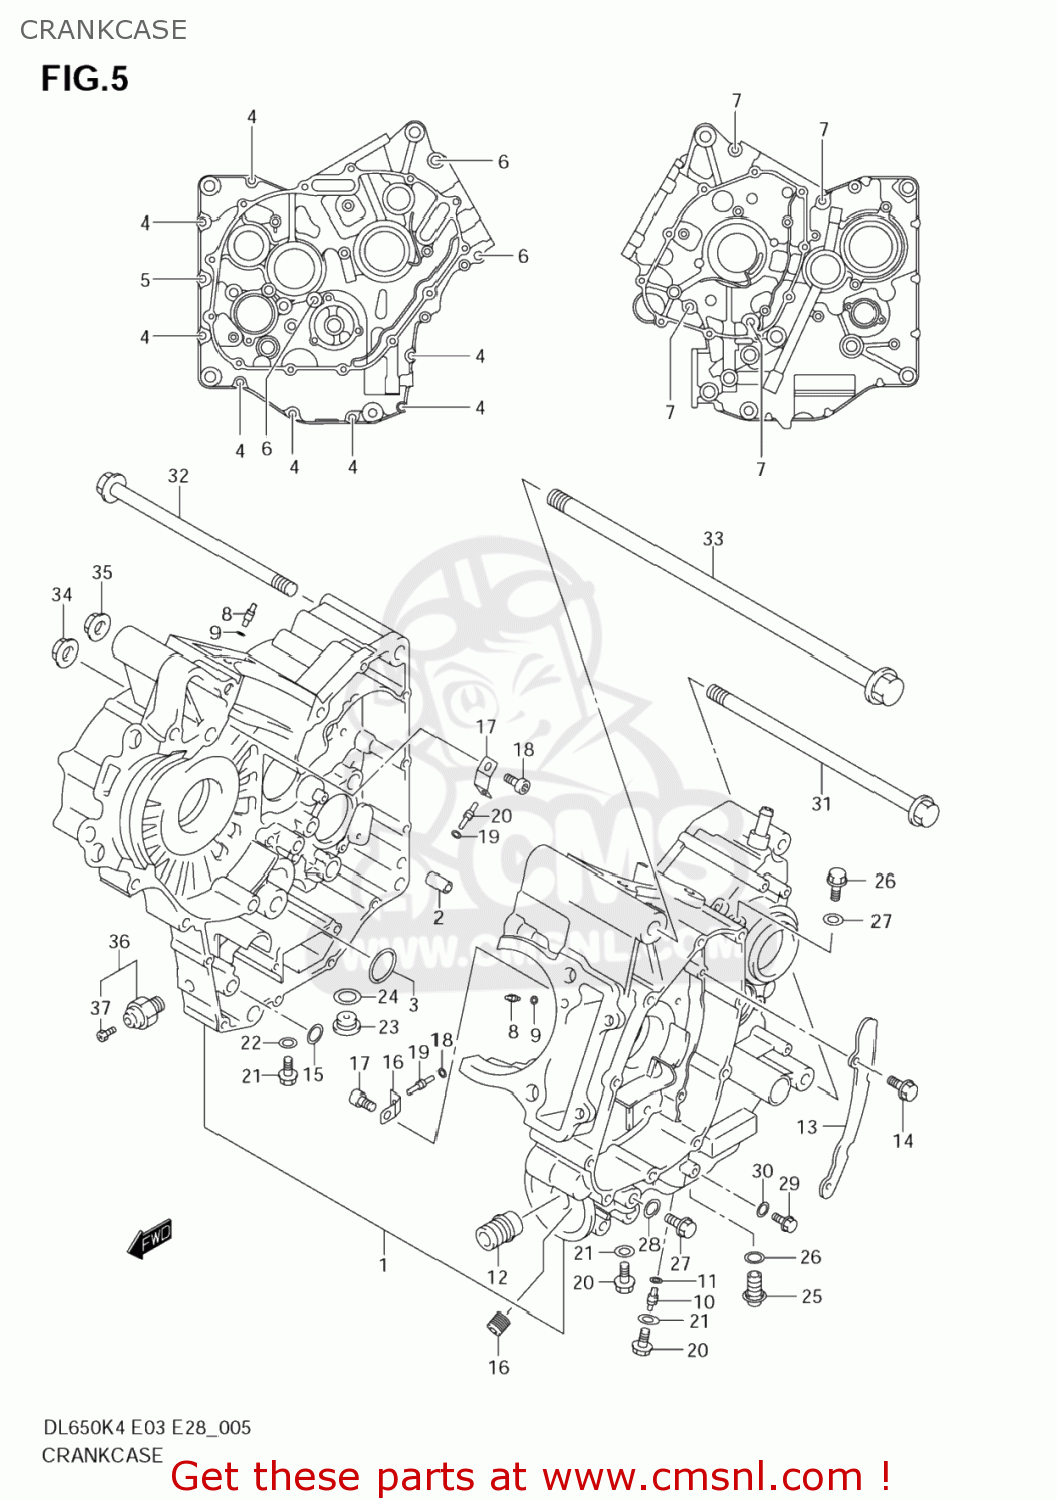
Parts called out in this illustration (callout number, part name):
1	CRANKCASE SET
2	PIN(8.4X11X20)
3	O RING(D:2.4,ID:15.8)
4	BOLT
5	BOLT
6	BOLT
7	BOLT
8	JET,AIR(14)
9	O RING(D:1.2,ID:4)
10	JET,AIR(14)
11	O RING(D:1.2,ID:4)
12	UNION,OIL STAND
13	PLATE,OIL SEPARATOR
14	BOLT
15	O RING(D:1.9,ID:12.6)
16	JET,OIL GALLERY(3.6)
17	PLATE,PISTON COOLING JET
18	BOLT(6X12)
19	O RING(D:1.2,ID:4)
20	JET(13)
21	BOLT
22	GASKET(8.2X14X1) (NAS)
23	PLUG,16X8
24	GASKET(16X22X2) (NAS)
25	PLUG(12X20)
26	GASKET(12.1X16.2X3.7) (NAS)
27	PLUG(12X10)
28	GASKET(12X17X1) (NAS)
29	BOLT
30	GASKET(5.8X13X1.2) (NAS)
31	BOLT(10X275)
32	BOLT(10X225)
33	BOLT(12X310)
34	NUT
35	NUT
36	SWITCH ASSY,OIL PRESSURE
37	BOLT,OIL PRESSURE SWITCH
